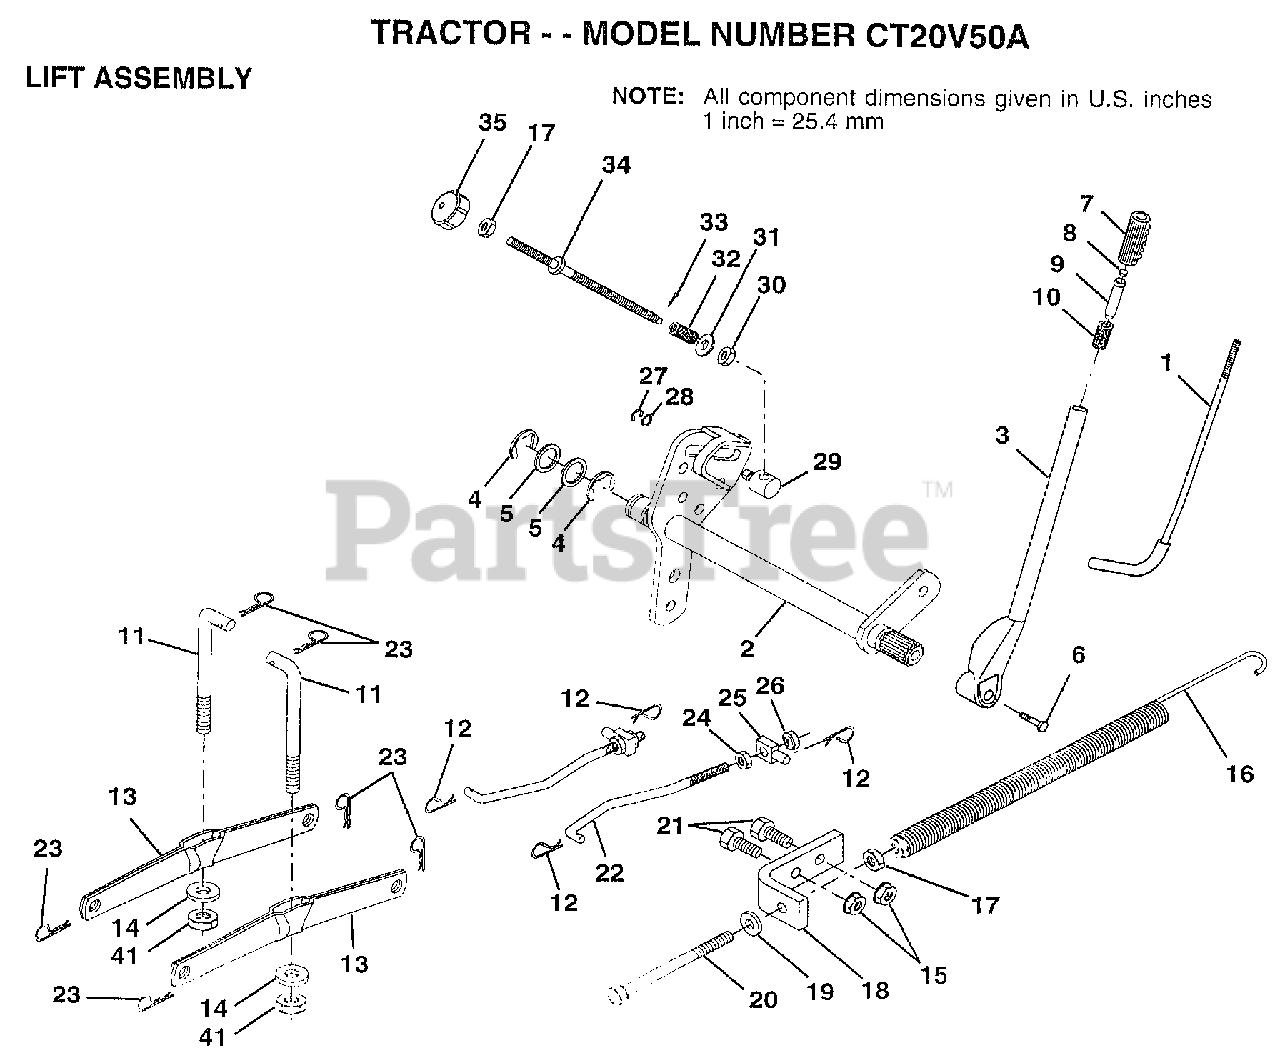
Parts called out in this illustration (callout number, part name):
1	LEVER ROD LT
2	SHAFT.LIFT.VGT.95
4	E-RING
5	WASHER
6	"BOLT,HEX"
7	GRIP
8	BUTTON PLUNGER YELLOW
10	SPRING T
11	LINK.LIFT.MWR.VGT
12	RETAINER.SPRING
13	ARM SUSP REAR
14	BEARING PVT LH
17	NUT
18	BRACKET SPRING AS
19	WASHER
20	BOLT-ADJ SPRING T
21	BOLT
22	LINK.FRONT
24	NUT
25	TRUNION
26	NUT.LK.W/WSH.1/2.
27	KLIP RING
28	WASHER
29	TRUNION LT
30	NUT T
31	WASHER
32	SPRING.COMP.INF.H
34	ROD.ADJ.LIFT
35	KNOB INF 3/8-16
41	NUT.CROWNLOCK.3/8
